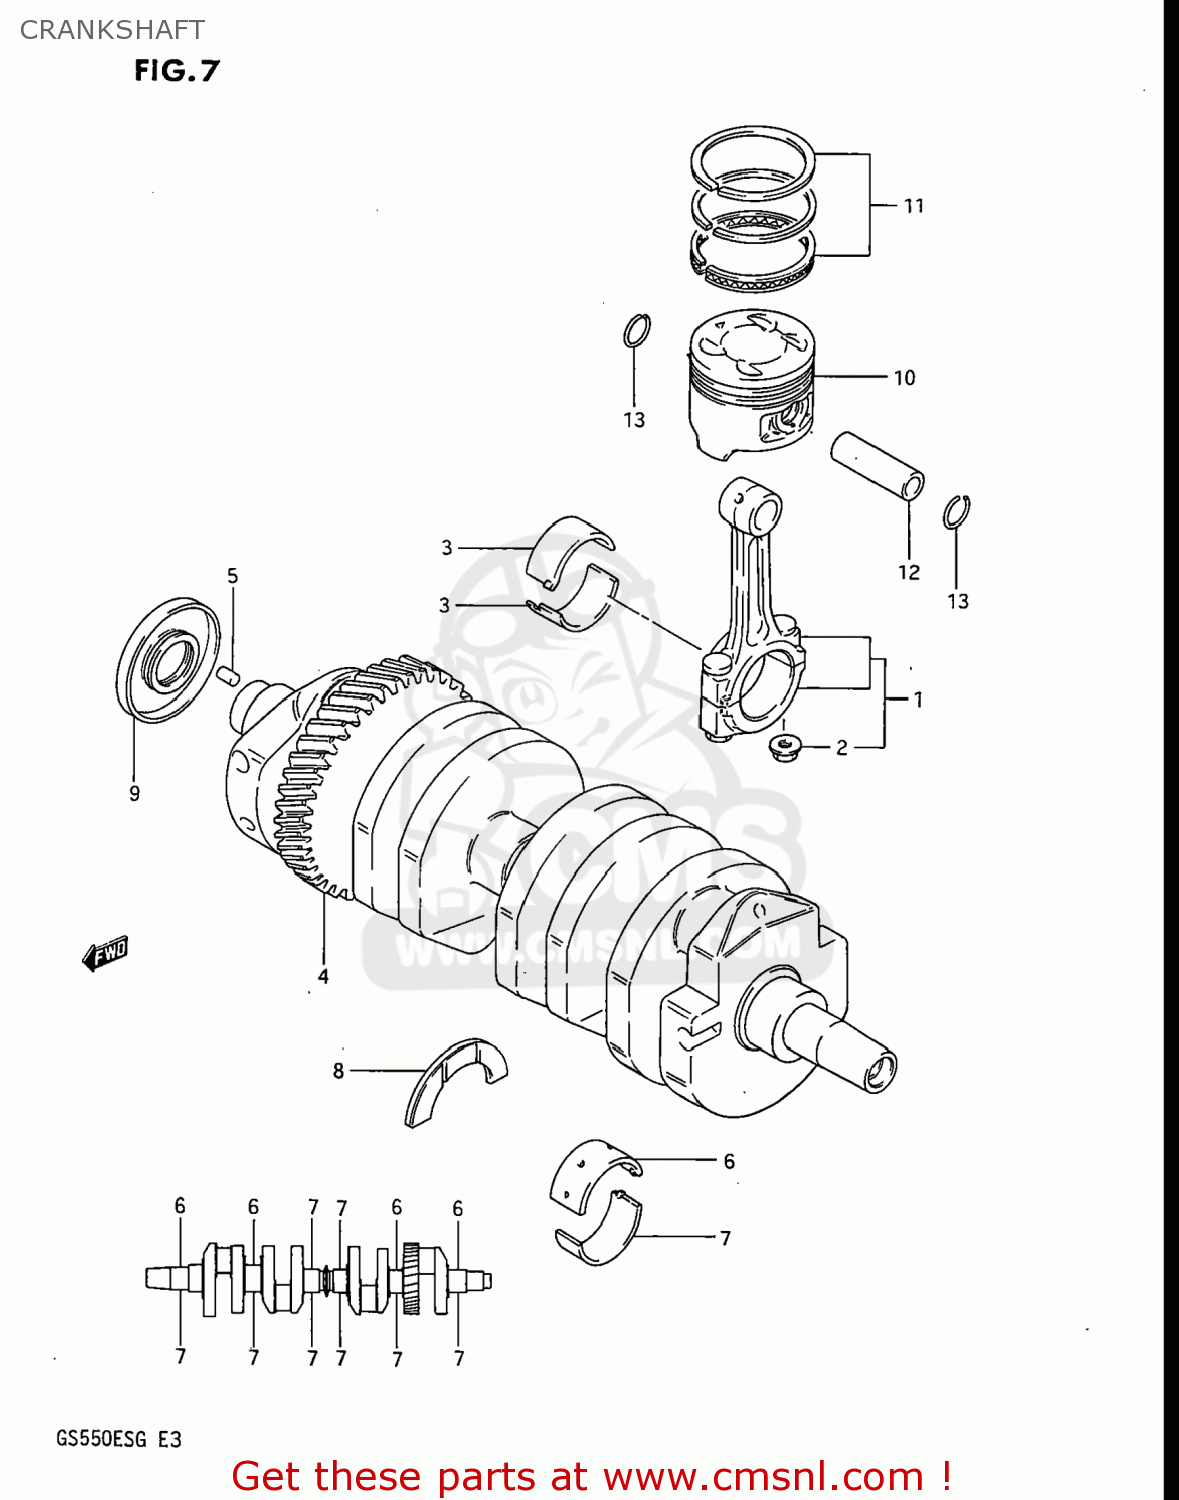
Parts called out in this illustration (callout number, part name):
1	ROD ASSEMBLY,CONNECTING
2	NUT
3	BEARING,CRANK PIN
4	CRANKSHAFT ASSEMBLY
5	PIN
6	BEARING,CRANKSHAFT
7	METAL CRANKSHAFT
8	PLATE,CRANK THRUST
9	OIL SEAL
10	PISTON
11	RING SET,PISTON
12	PIN,PISTON
13	CIRCLIP
